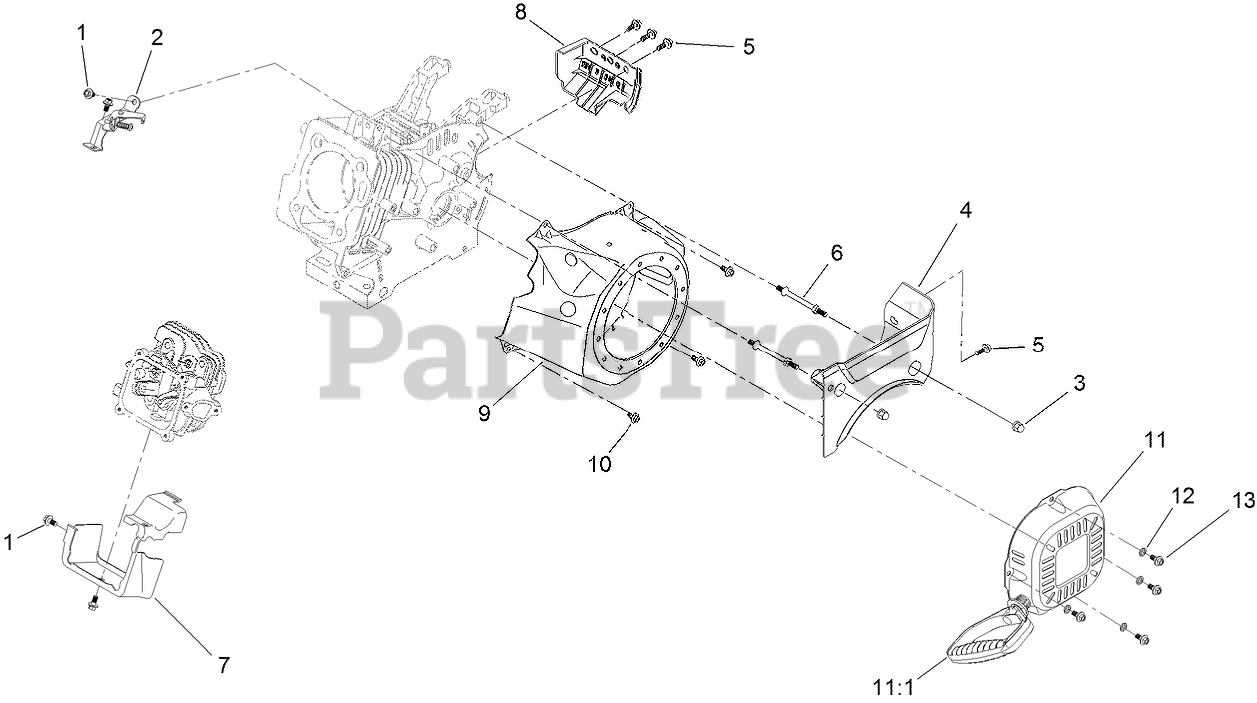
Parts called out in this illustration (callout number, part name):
1	SCREW-HHF
2	THROTTLE CONTROL ASM
3	NUT-ACORN
4	PANEL-FRONT
5	SCREW-HHF
6	STUD-MOUNT
7	SHROUD-HEAD
8	PANEL-SIDE, ENGINE
9	SHROUD-FLYWHEEL
10	SCREW-HHF
11	RECOIL ASM
11:1	HANDLE-RECOIL
12	WASHER-PLAIN
13	SCREW-HHF
